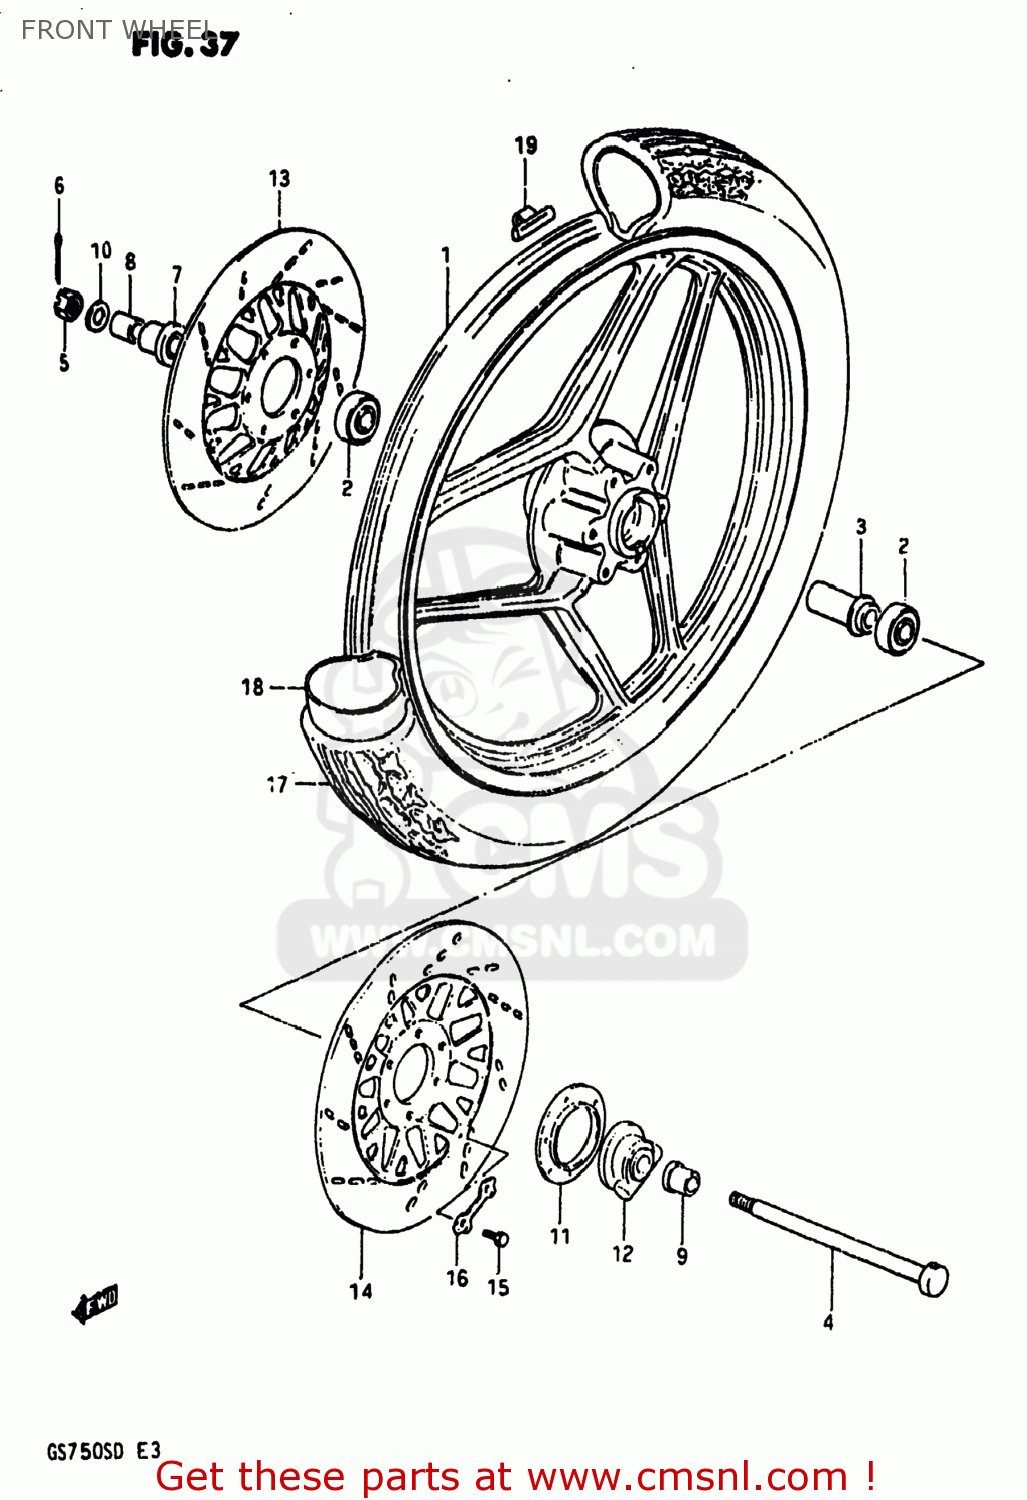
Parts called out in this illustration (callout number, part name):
1	CASTING WHEEL,FRONT 1.85
2	BEARING
3	SPACER,FR HUB BEARING
4	AXLE,FR
5	NUT 12MM
6	COTTER PIN
7	SPACER,FR AXLE,R
8	SPACER,FR AXLE,R
9	SPACER,FR AXLE,L
10	WASHER
11	DUST SEAL,SPEEDOMETER GEAR BOX
12	BOX ASSEMBLY,SPEEDOMETER GEAR
13	DISC,FR BRAKE,R
14	DISC,FR BRAKE,L
15	BOLT(8X25)
16	WASHER
17	TIRE,FRONT
18	TUBE,INNER
19	BALANCER,WHEEL
